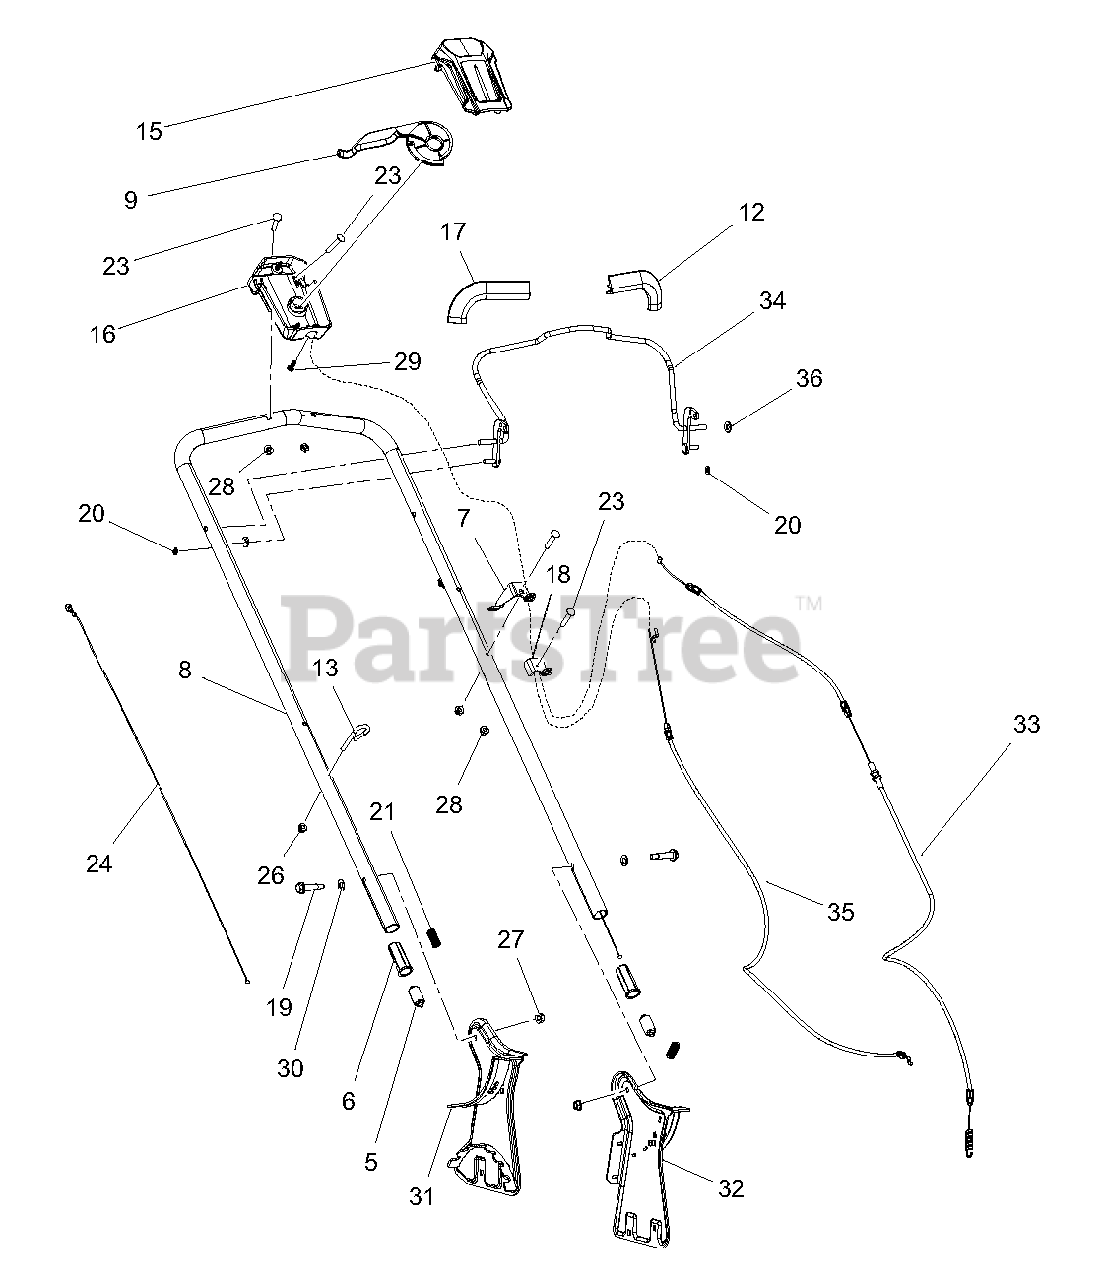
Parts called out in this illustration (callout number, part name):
5	PIN, LM HANDLEBAR LOCKING
6	HANDLEBAR ADJUSTMENT INSERT
7	BRKT, CABLE ANCHOR
8	HANDLEBAR,
9	HANDLE, DRIVE CONTROL
12	GUARD, FINGER - LH
13	GUIDE, RECOIL ROPE
15	HOUSING, UPPER DRIVE CONTROL
16	FRONT SQUEEZE BOX
17	GUARD, FINGER - RH
18	BRKT, CABLE - DRIVE
19	BLT, SHLDR .50 X 1.30 X .38-16
20	PUSH-NUT 1/4
21	SPRG, COMPRESSION
23	BLT-RDHDSQNK-GR5-Y
24	ADJUSTABLE HANDLEBAR CABLE
26	NUT-LK-NYL-FLG .25-20 YWZC
27	NUT,LK-TOP-FLG
28	Nut-Hex Top Lock Flange
29	SCR-TAP #12-14X.75 PLASTITE BLZC
30	WSHR-FL-STL .385x.745x.030 YWZC
31	WLDMT, RH SIDE PLATE
32	WLDMT, LH SIDE PLATE
33	CABLE, DRIVE CONTROL
34	BAIL, OPC
35	CABLE, OPC
36	@WSHR-FL-STL.344X.688X.065YWZC
